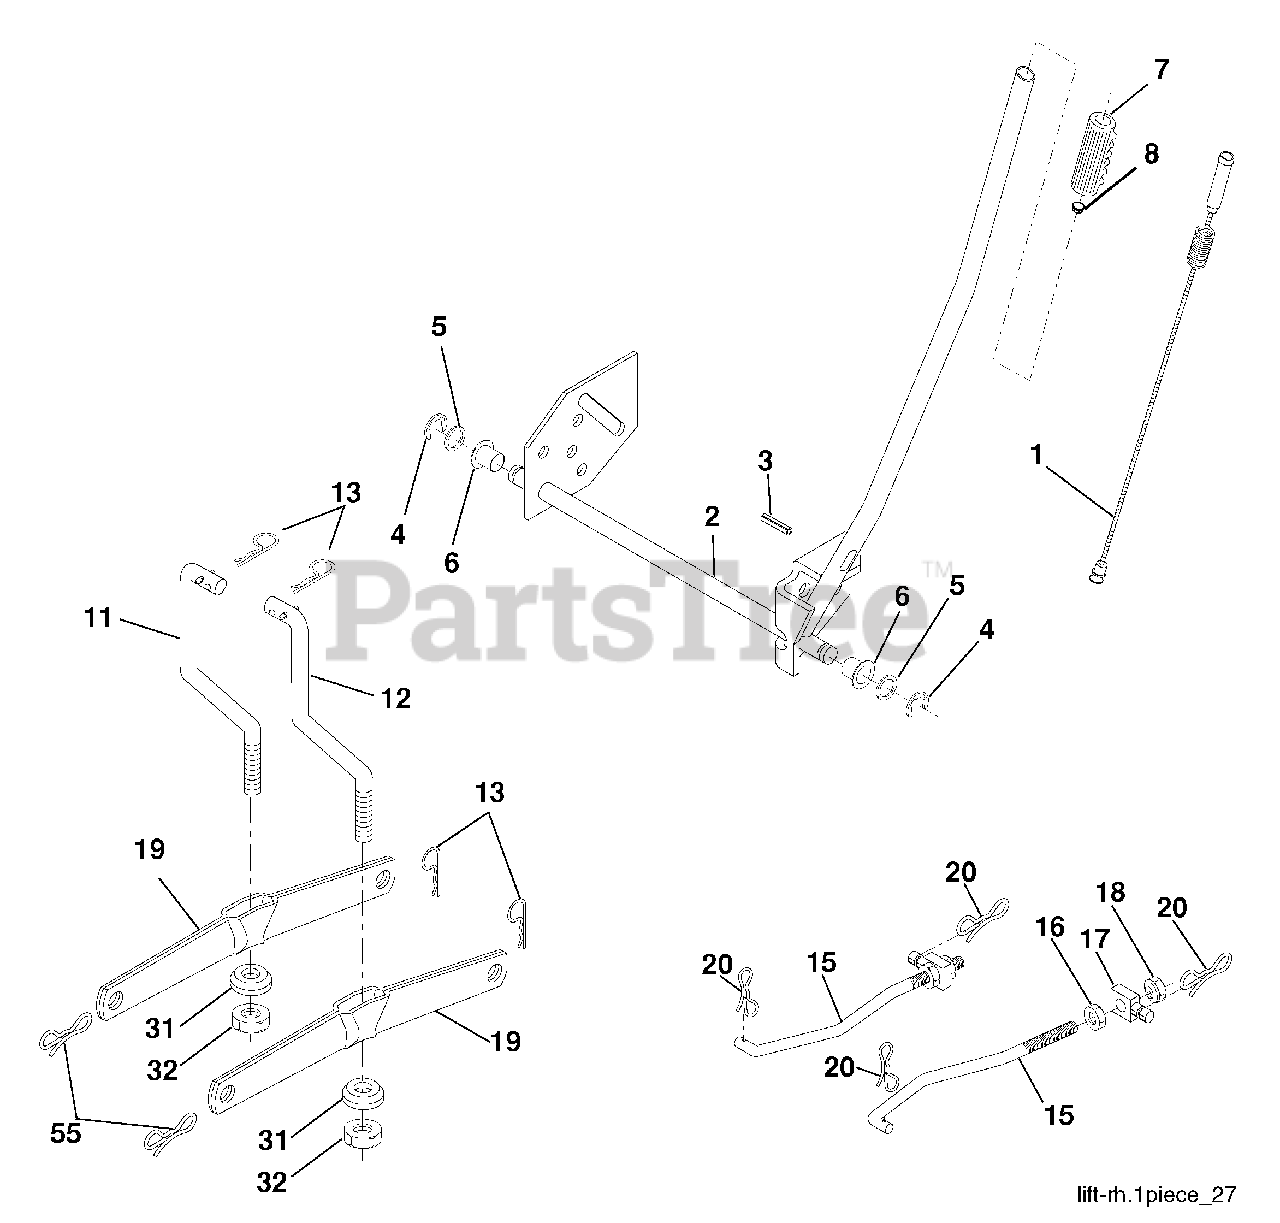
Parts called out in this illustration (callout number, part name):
1	Plunger Asm Lift Lever
2	Shaft Asm Lift RH
3	Pin Groove 1 500 Zinc
4	E Ring #5133-62
5	Washer 21/32 x 1 x 21 Ga.
6	Bearing Nylon Blk 629 Id
7	Grip Handle Bicycle Matte Blk
8	Button Plunger Black
11	Link Lift LH Fixed Length
12	Link Lift RH Fixed Length
13	Retainer Spring
15	Link Front
16	Nut Jam Hex 1/2-13 unc
17	Trunnion
18	Nut Lock w/Wsh 1/2-13 unc
19	Arm Suspension Rear
20	Pin Cotter 7/16 Bow Tie Lock
31	Bearing Pvt Lift
32	Nut Crownlock 3/8-24
55	Pin Cotter 5/16
